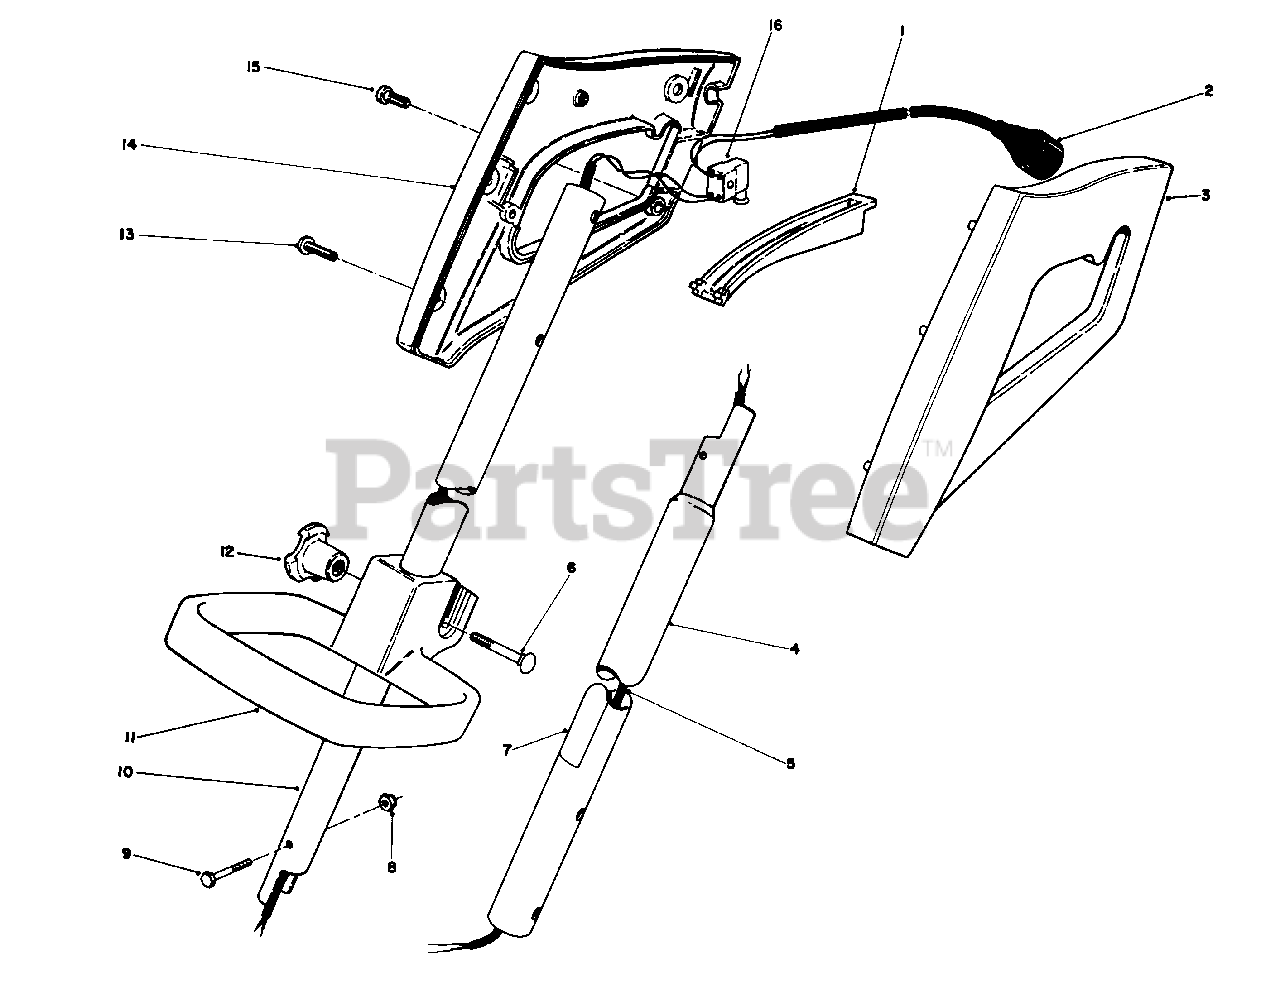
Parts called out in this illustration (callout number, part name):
1	Bar Switch
2	Power Cord
3	Grip-Left Handle
4	Tube-Lower
5	Wiring Harness
6	Carriage Bolt
7	Decal-Serial No. Replacement
9	Machine Screw
10	Tube-Upper
11	Adjustable Handle
12	Knob
13	Screw
14	Grip-Right Handle
15	Screw-Thread Forming
16	Switch-Single Speed
